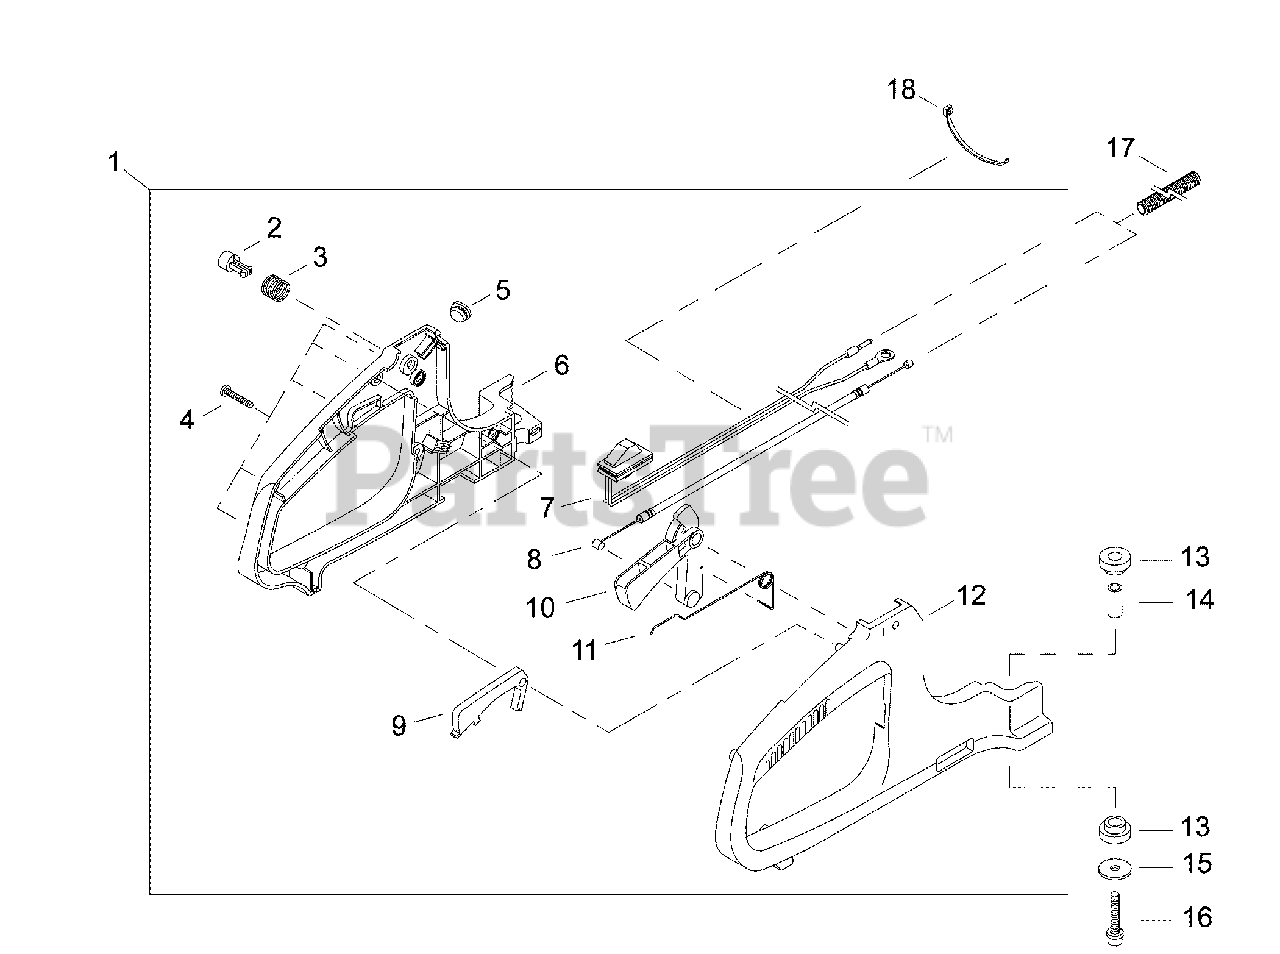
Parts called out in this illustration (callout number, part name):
1	HANDLE ASSY, REAR
2	BUTTON, THROTTLE LOCK
3	SPRING, COMPRESSION
4	SCREW, TAPPING Ø4×18
5	PLUG, RUBBER
6	CONTROL HANDLE - LEFT
7	SWITCH, ON-OFF
8	CABLE ASSY, THROTTLE
9	LEVER, THROTTLE LOCKOUT
10	TRIGGER, THROTTLE
11	SPRING, THROTTLE RETURN
12	CONTROL HANDLE - RIGHT
13	CUSHION
14	COLLAR 6
15	WASHER Ø23ר6.5×2 MM
16	BOLT M6×35
17	TUBE, FLEXIBLE
18	STRAP, TIE
